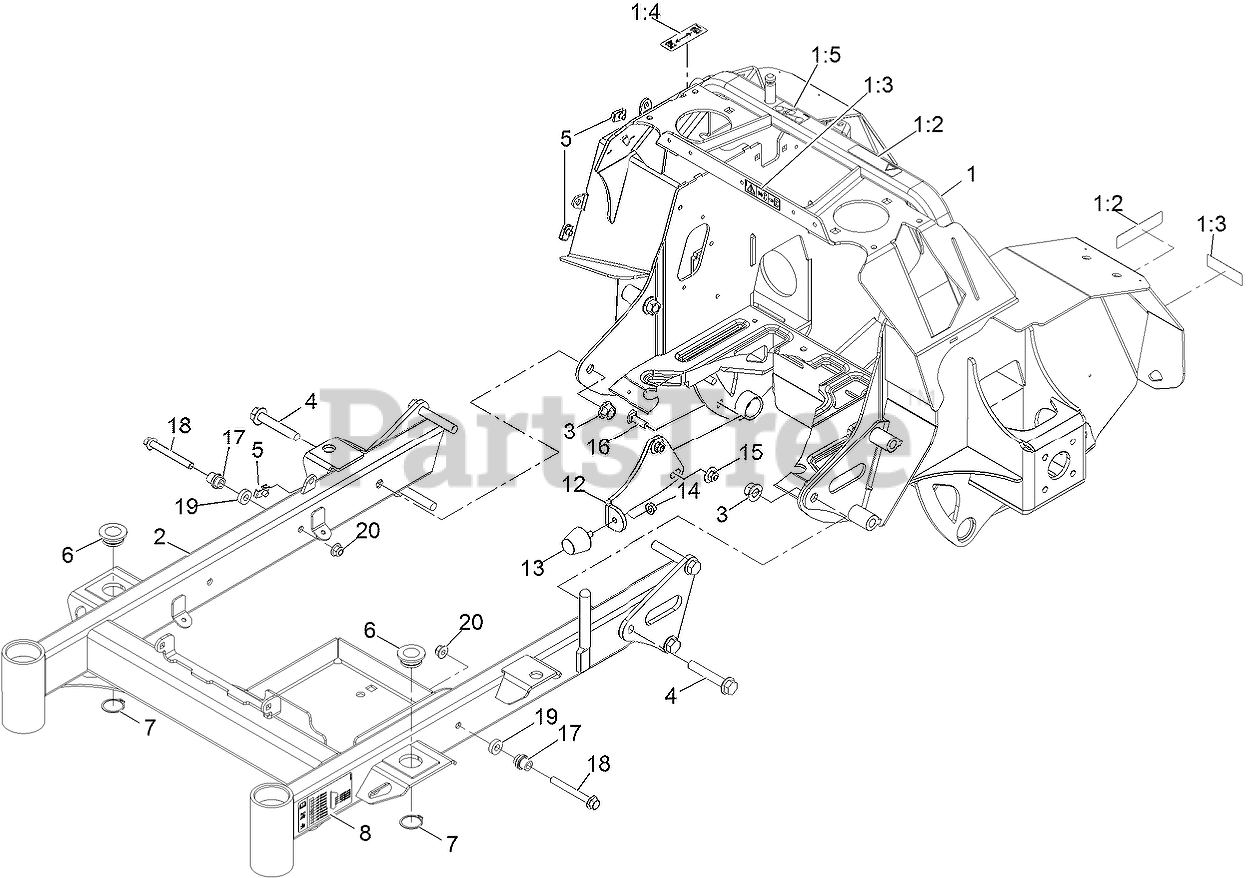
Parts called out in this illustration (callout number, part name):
1	ASM-Frame
1:2	DECAL-WARNING
1:3	DECAL, COVER MISSING
1:4	DECAL-BRAKE, PARKING
1:5	DECAL-BELT ROUTING HYD
2	ASM-Frt Frame 32/36 [red]
3	Nut-Lock 1/2-13
4	SCREW-HF
6	BUSHING-DECK
7	RING-RETAINING
8	Decal-Height Of Cut Sm
12	Bracket-Bumper 32
13	BUMPER-RUBBER
14	NUT-HF, NI
15	Nut-Nyloc 3/8-16 Flg
16	BOLT-CARR
17	Bushing-Latch
18	Screw-HHF
19	SPACER
20	NUT-HF, NI
